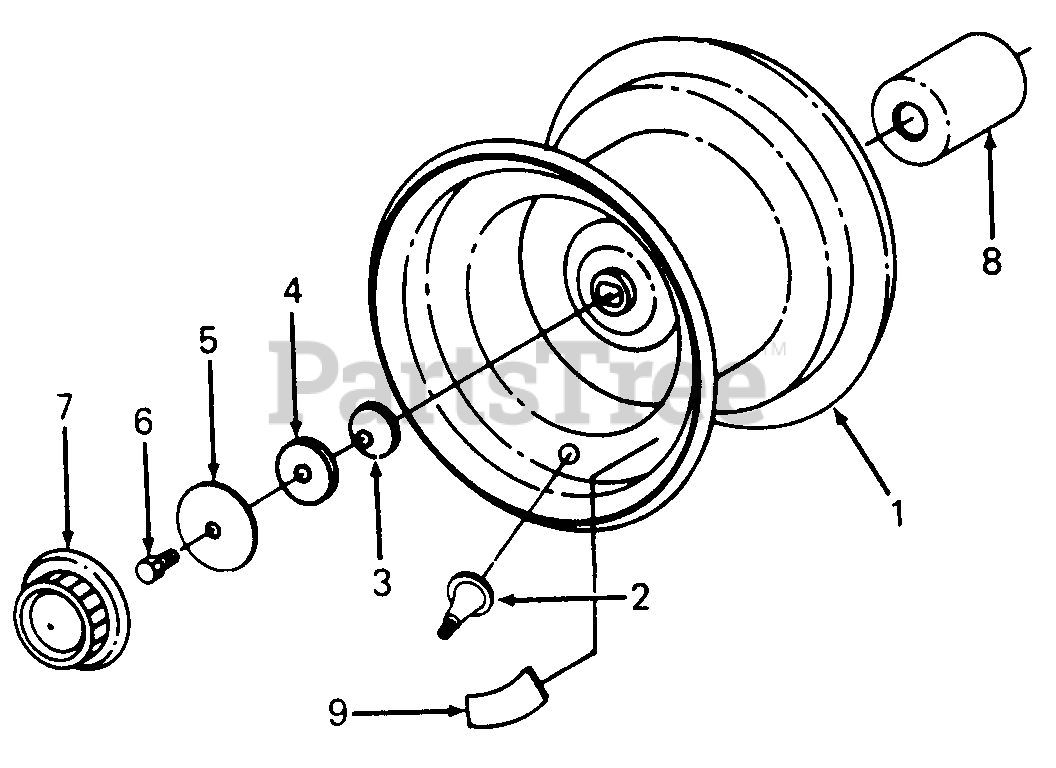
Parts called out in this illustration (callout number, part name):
1	Wheel Assy, Rear
2	Valve, Tubeless Type
3	Washer, .345 X .88 Belleville
4	Washer, .344 X 1.125 X .125
5	Washer, .406 X 1.92 X .06
6	Bolt, 5/16 X 1 GR 5
7	Cap, Hub
8	Spacer, Transmission
9	Label, Inflation
